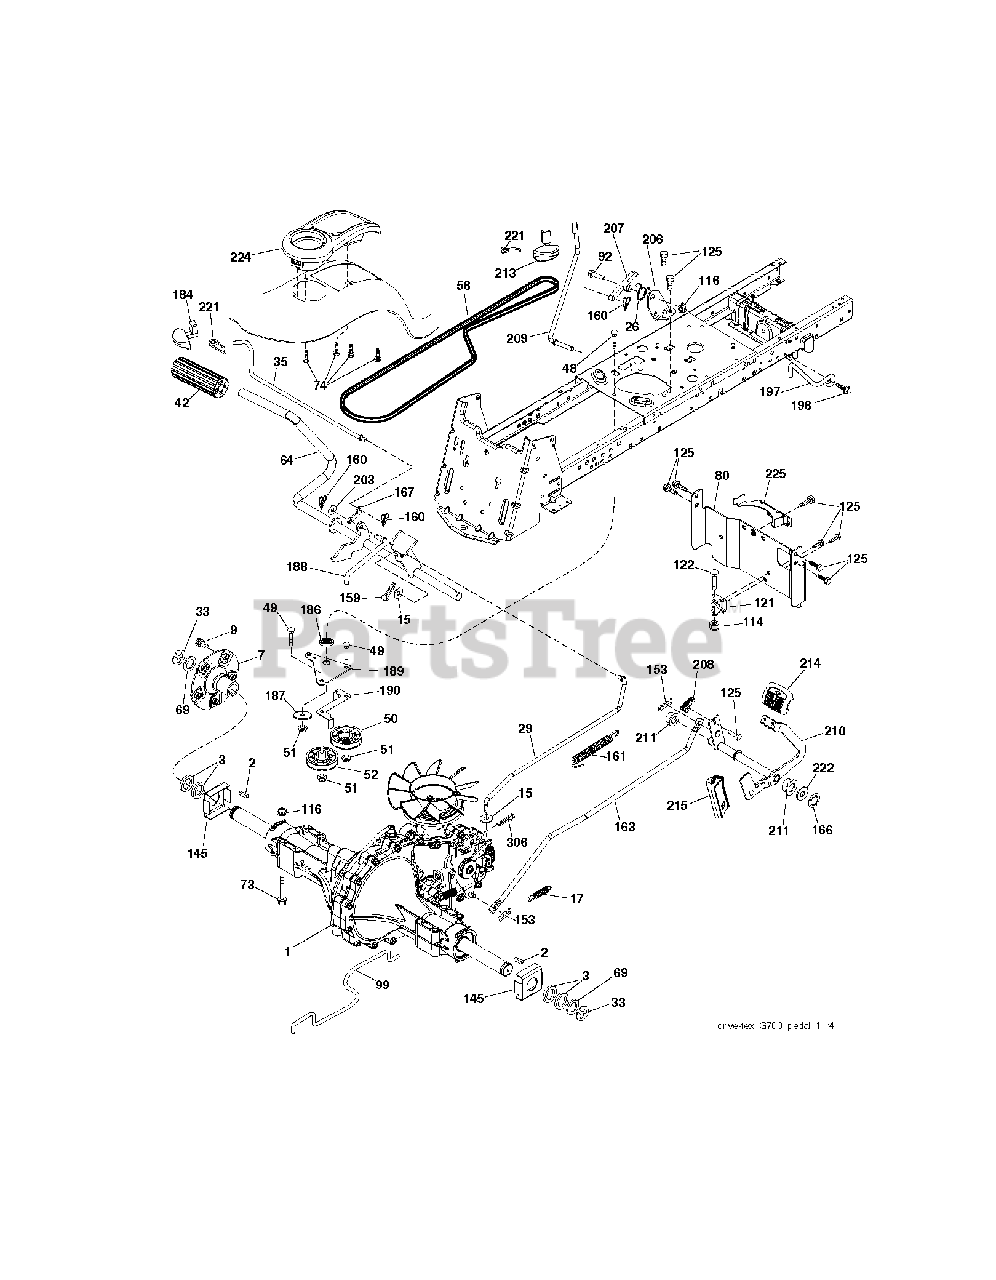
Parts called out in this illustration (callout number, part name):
7	HUB.ASM.WHEEL.REAR.23"TEX
17	SPRING.BRAKE.HG3000/3500
26	SPRING.RETURN.CRUISE
29	ROD BRAKE
33	E RING HYT
35	ROD.BRAKE.PARTK.HUSQ.TEX
42	PEDAL COVER T
48	BOLT.3/8-16X1.50
49	BOLT
50	IDLER.FLAT.910.OFFSET
51	NUT LOCK FLG 3/8-16 UNC
52	IDLER.V-GROOVE.910.OFFSET
56	DRIVE BELT, LTH & YTH TRACTORS
64	SHAFT.ASM.PEDAL.BRK.CNTR
74	SCREW.HI-LO.CONSOLE
80	STRAP.TORQUE.YT.G700
92	BOLT
99	SPRING.BYPASS.YT.G700
114	NUT.71038.31-18.HEX.NYLOCK
116	NUT LOCK HEX FLANGE 5/16-18
121	BRACKET STRAP TORQUE
122	BOLT.5/16-18X2.5
125	SCREW
153	RETAINER M
159	COTTER PIN
160	RETAINER CLIP
161	SPRING, RETURN LT
163	ROD PEDAL CONTROL
166	NUT.PUSH.625
167	LATCH.BRAKE.SPRING
184	HANDLE.PARKG.BRK.HUSQ/PRED.667
186	SPACER.RETAINER
187	WASHER 12/32X2X10GA
188	LINK.CLUTCH.GROUND.DRIVE
189	BELLCRANK.GROUND.DRIVE.TRAPPED
190	KEEPER BELLCRANK ROUND DRIVE
196	SCREW 3/8-16X1
197	BRKT.ANIT-ROTATION.CLU
203	WASHER
206	BRKT.MOUNT.LATCH.CRUIS
207	LATCH.CONTROL.CRUISE
208	GEAR.SECTOR.CONTROL.CR
209	ROD.CONTROL.CRUISE.GT.
210	ROCKER.ASM.PEDAL.CONTR
211	BEARING.NYLON
213	KNOB.CONTROL.CRUSIE.HU
214	PAD PEDAL FORWARD
215	PEDAL.REVERSE.TEX.GT.4
221	RETAINER.SPRING.CLIP.H
222	WASHER 21/32 X 1-1/4 X 10 GA.
224	CONSOLE.TOOLBOX.PCH.ERGO.BLACK
306	PIN COTTER
